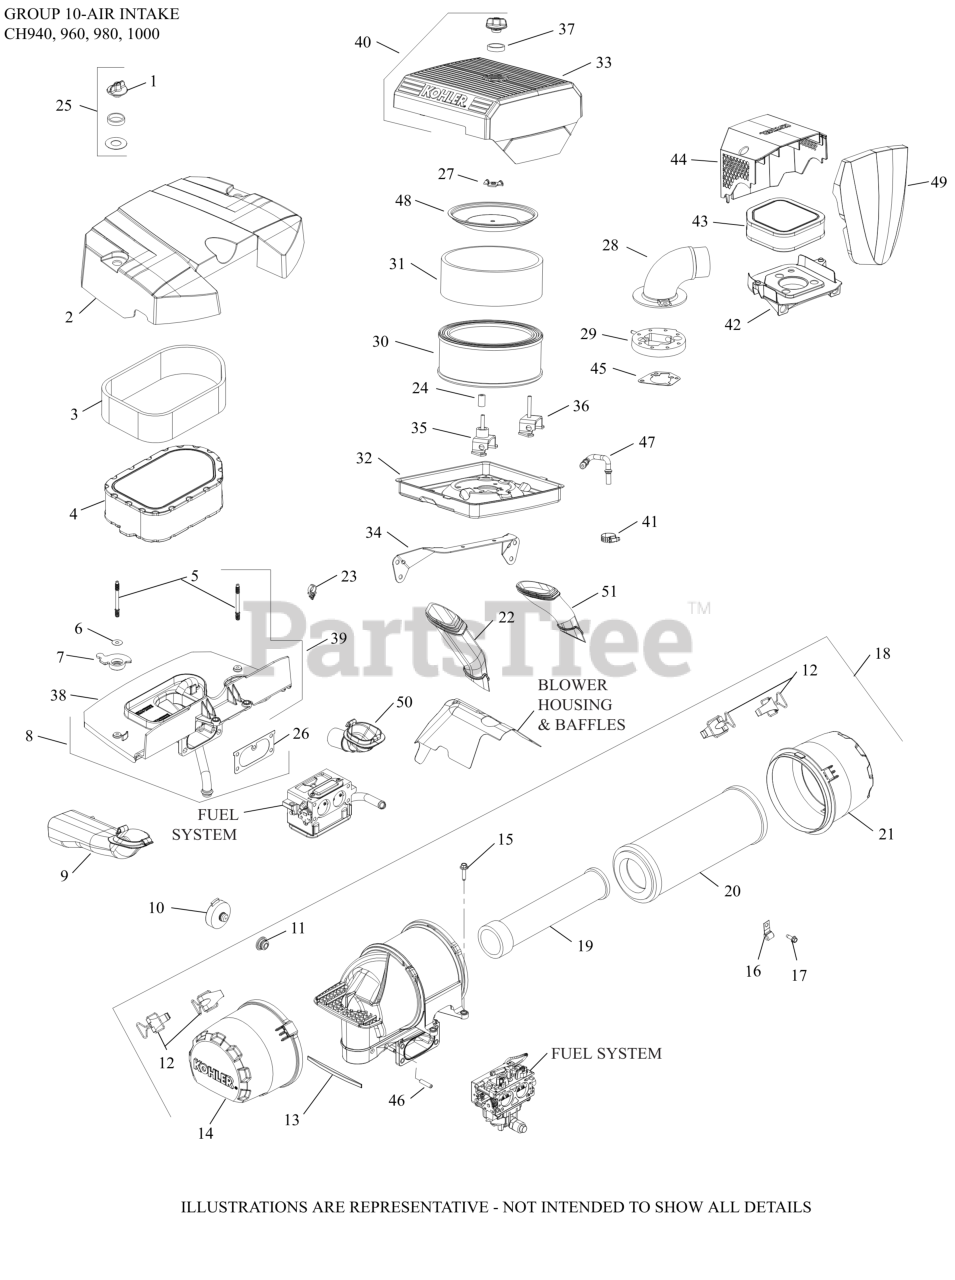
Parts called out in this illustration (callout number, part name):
1	KNOB, COVER
2	COVER, AIR CLEANER
3	ELEMENT, PRE-CLEANER
4	ELEMENT, AIR FILTER (LPAC)
5	STUD, AIR CLEANER BASE
8	KIT, AIR CLEANER BASE
15	SCREW, FLG M6X1.0X25
25	KIT, KNOB W/SEAL
26	GASKET, AIR CLEANER ELBOW
